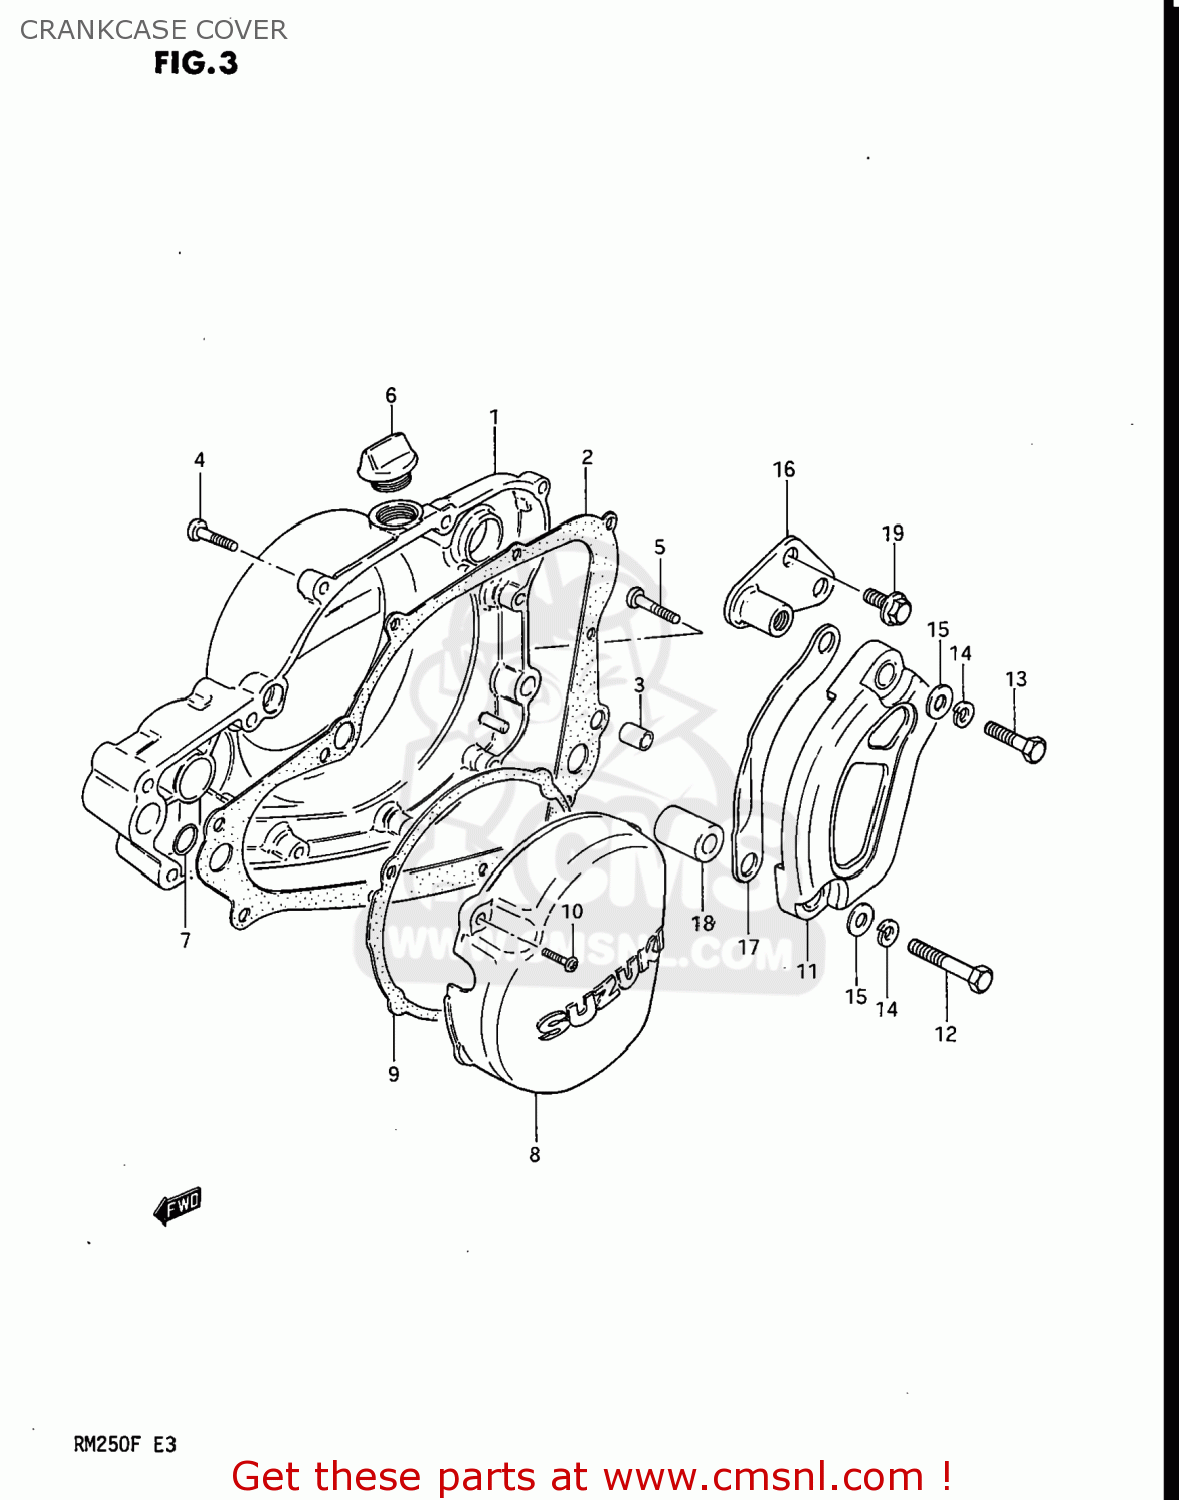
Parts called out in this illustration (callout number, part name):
1	COVER,CLUTCH
2	GASKET,CLUTCH COVER (MCA)
3	PIN
4	SCREW
5	SCREW
6	PLUG SET
7	O RING(D:2.4,ID:16.8)
8	COVER,MAGNETO
9	GASKET,MAGNETO COVER (MCA)
10	SCREW
11	COVER,SPROCKET
12	BOLT 8X55
13	BOLT
14	LOCK WASHER
15	WASHER,8.5X16X
16	BRACKET,CHAIN GUIDE PL
17	PLATE,FRONT CHAIN GUIDE
18	SPACER (8.6X16X23.5)
19	BOLT
